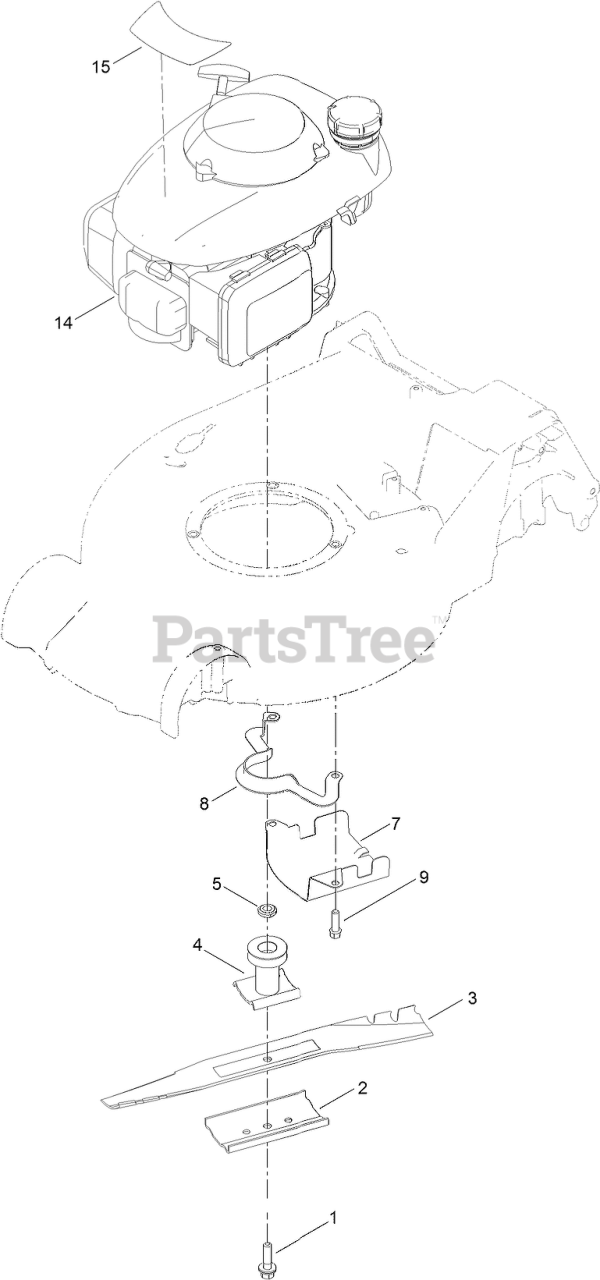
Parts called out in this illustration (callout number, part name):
1	BOLT-BLADE
2	SUPPORT-BLADE
4	DRIVER-BLADE
5	SPACER-DRIVER
7	SHIELD-GRASS
8	GUIDE-BELT
14	ENGINE-HONDA,GCV160A0-S3TE GAS
15	DECAL-ENGINE
